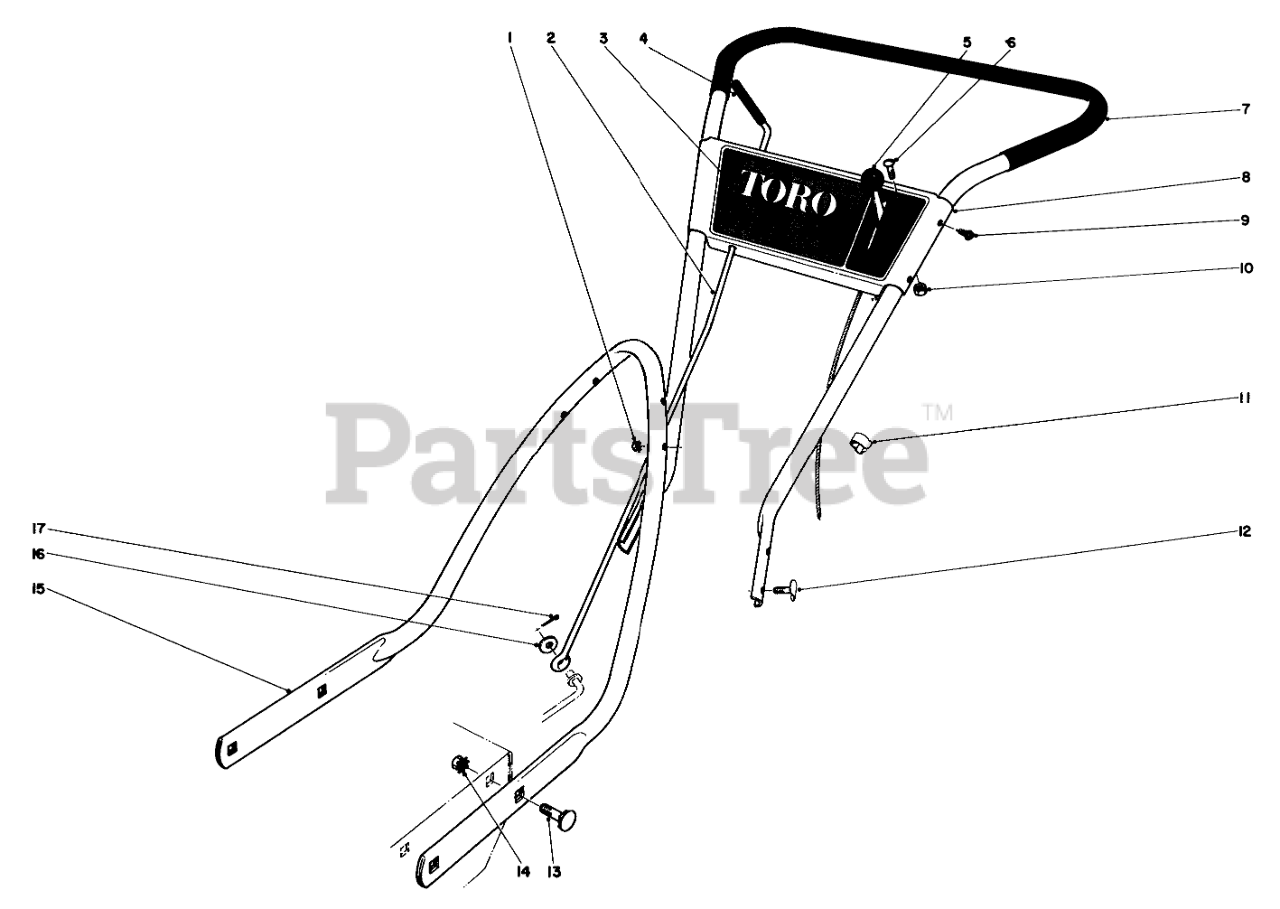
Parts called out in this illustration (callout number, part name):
1	NUT-KEPS
2	Rod, Traction Control
3	Decal
5	Control, Throttle
6	SCREW-PPH
7	Handle, Upper Assembly
8	Plate, Escutcheon (Incl. Ref. No. 3)
9	SCREW-HWHTF
10	Nut
13	BOLT-CARR
15	Handle, Lower
16	WASHER-FLAT
17	PIN-COTTER
